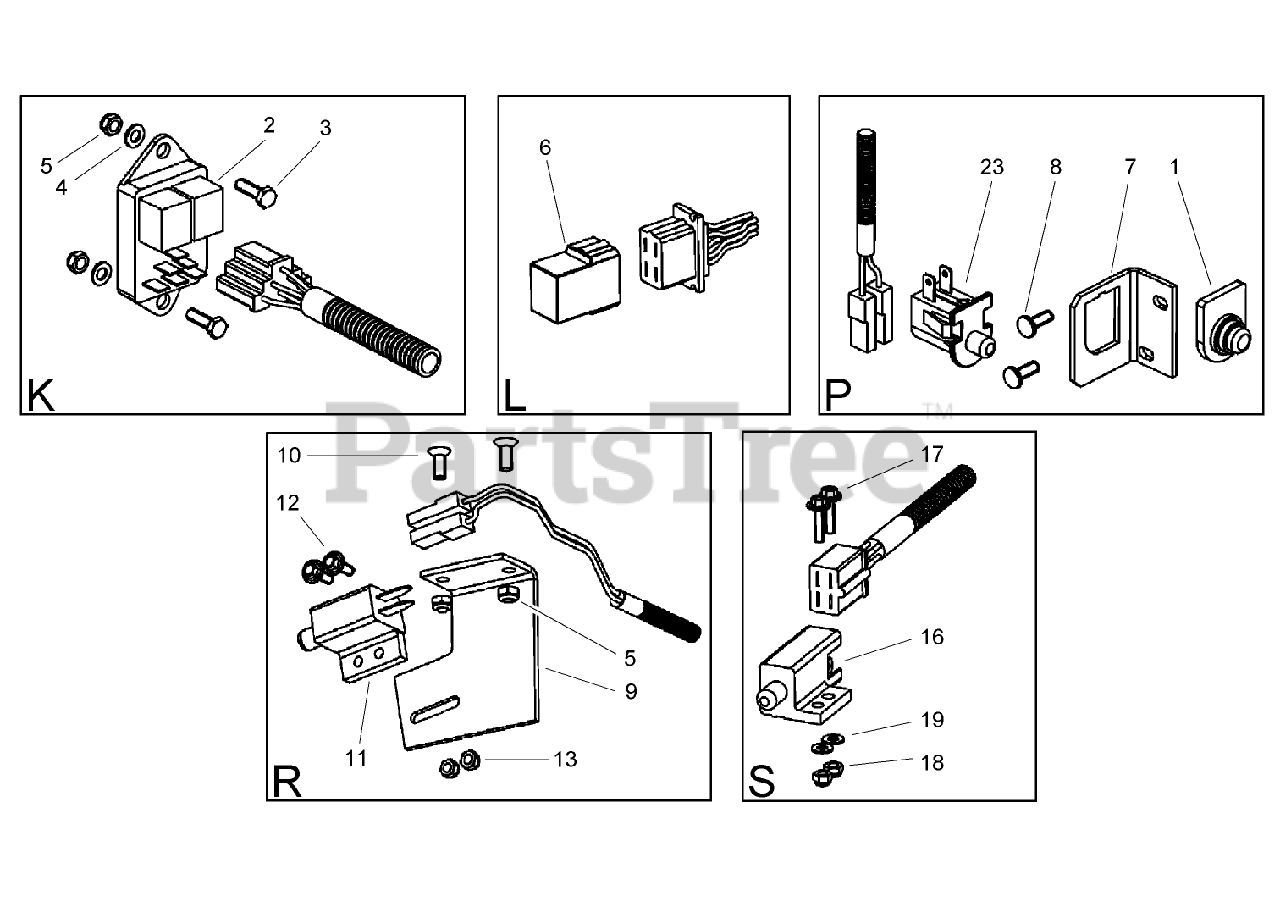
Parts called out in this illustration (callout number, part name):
1	COVER-PROTECTIVE
2	MODULE-CLUTCH
3	SCREW-HH
4	WASHER
5	NUT-LOCK
6	CIRCUIT-MEMORY
7	HOLDER-SWITCH
9	HOLDER-SWITCH
11	SWITCH-POLE, SINGLE
13	NUT-HEX
16	Switch-Delta
18	NUT-LOCK
19	WASHER
23	SWITCH-DELTA
